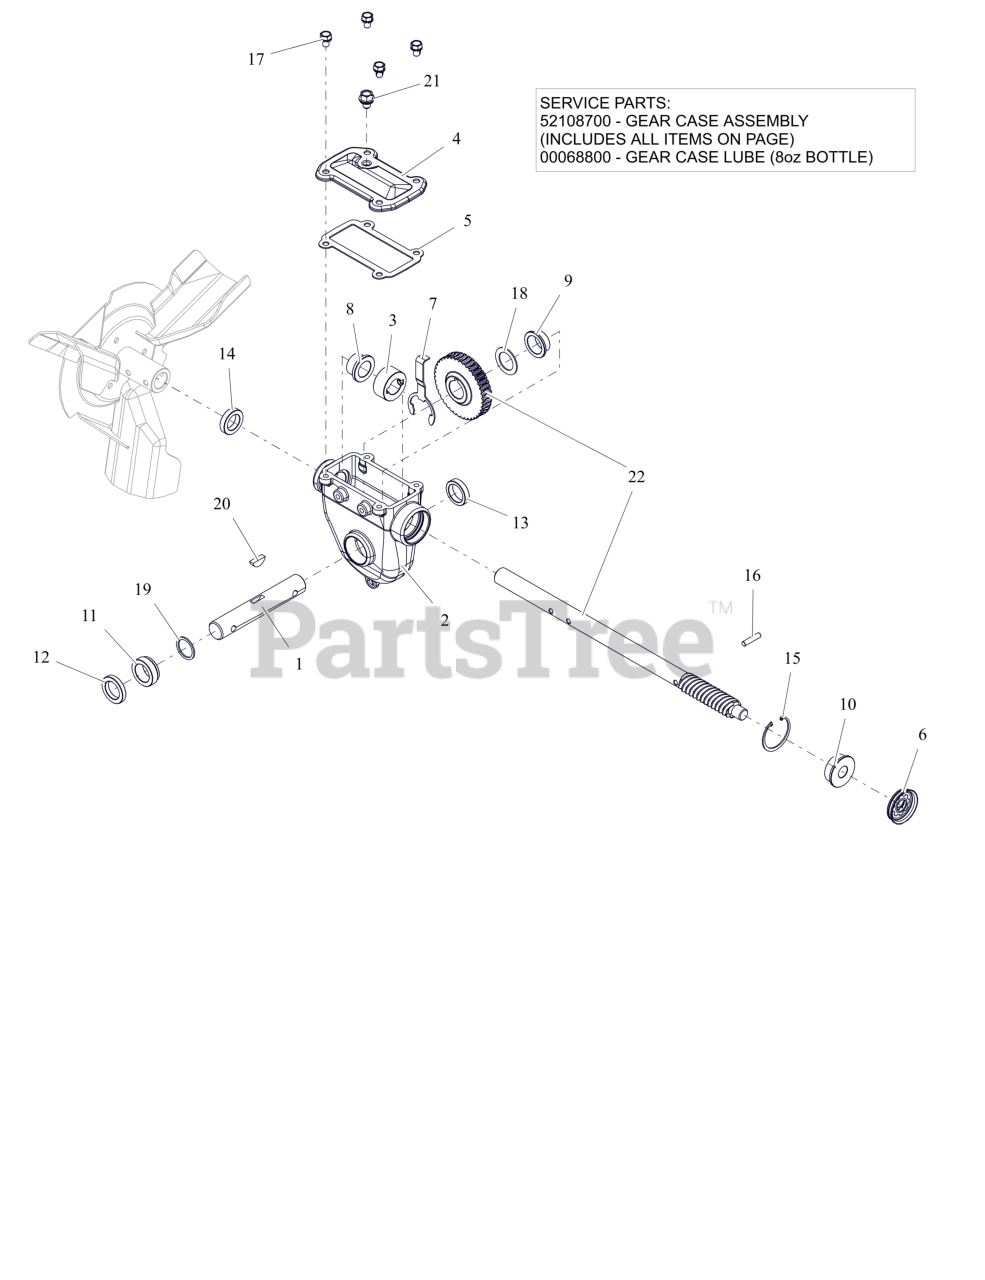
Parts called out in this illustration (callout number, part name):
1	RAKE SHAFT, SHORT-COMMON
2	GEARCASE, LARGE MACHINED
3	THRUST COLLAR, .875"ID SLIPFIT
4	COVER, TOP - LARGE IRON
5	GASKET, TOP - LARGE GEARCASE
6	COVER, GEAR CASE 1.75"
7	BUSHING RETAINER, LARGE
8	BSHG-FLG .879X1.128X.75X1.45
9	BSHG-FLG 1.006X1.128X.555X1.45
10	BSHG-FLG .628X1.503X.58X1.725
11	BSHG-FLG LARGE, RIGHT
12	SEAL-OIL .999X1.500X.250 TBC29
13	SEAL-OIL .999X1.375X.312 TBC29
14	SEAL-OIL .873X1.375X.312 TBC29
15	RG-RTNG-INT 1.750X.062
16	PIN-STR .250X1.12 6150
17	BLT, SEMS .31-18X.50 G5 ZCC
18	WSHR, FLT 1.010X1.505X.062 ZCC
19	WSHR, FLT 1.010X1.250X.068 ZCC
20	KEY-WDRF .25X.875 HRD #A
21	SCR, .380-15X.500 W/SEAL WASHER
22	KIT, SERVICE-WORM SHAFT & GEAR
